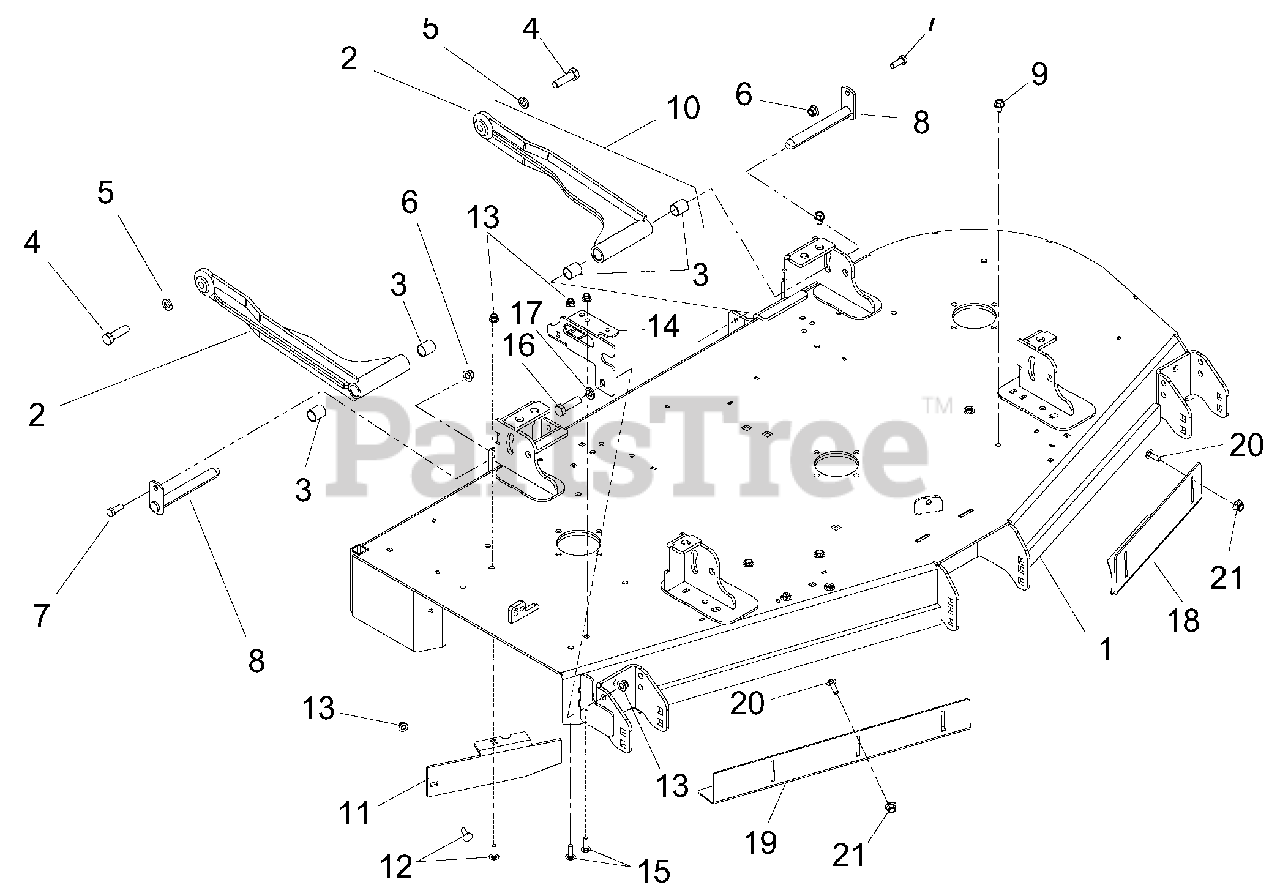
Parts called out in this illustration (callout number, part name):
1	WMT, 60in SIDE DISCH DECK (992236)
2	WMT, DECK STABILIZER ARM
3	BRG, .75 X .875 X 1.00
4	BLT-HEX .50-13X1.75 GR5 YWZC
5	WSHR-LK .50X.125 REG YWZC
6	NUT-LK-NYL-FLG .38-16 YWZC
7	BLT-HEX .38-16X1.00 GR5 YWZC
8	WLDMT, MOWER MTG. PIN
9	SCR-TAP .38-16X.50 HWH
10	PUSH ARM ASSEMBLY (INCLUDES ITEMS 2 AND 3)
11	60" BAFFLE (992236)
12	BLT-RDHDSQNK .31-18X1.00 G5YZ
13	NUT-LK-NYL-FLG .31-18 YWZC
14	BRKT, BAGGER REMOVEABLE
15	BLT-RDHDSHSQNK .31-18X1.00 G5YWZC
16	BLT-HEX .31-18X1.00 GR5 YWZC
17	WSHR-FL-STL .438X1.00X.083 YWZ
18	60" LH VACUUM BAFFLE - BLK (992236)
19	60" RH VACUUM BAFFLE - BLK (992236)
20	BLT-RDHDSQNK .31-18X.75 G5YZ
21	NUT-LK-NYL .312-18 YWZC
